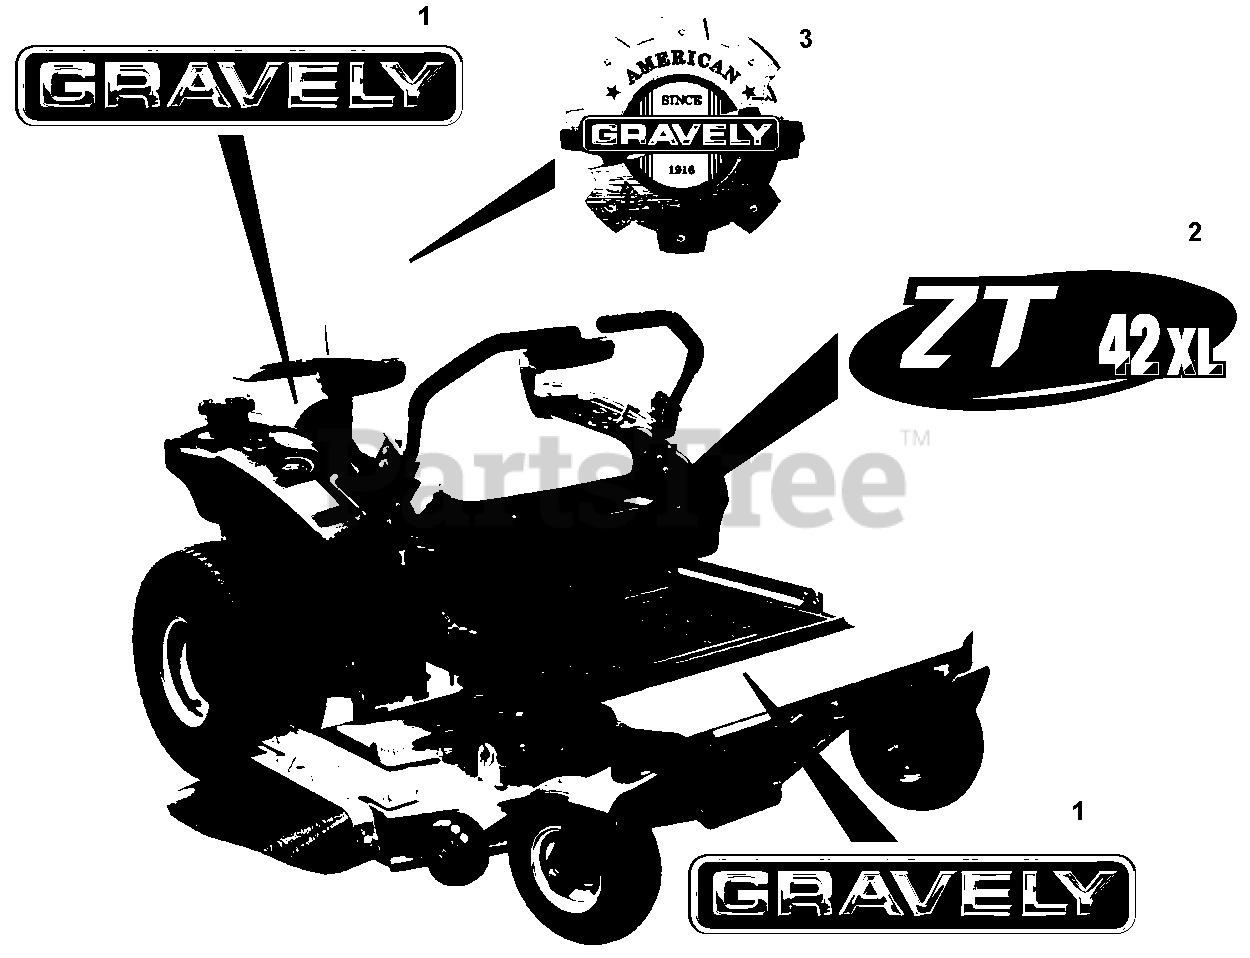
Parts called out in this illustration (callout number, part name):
1	Decal, Gravely Logo
2	Decal, 42 ZT XL
2	Decal, 48 ZT XL
2	Decal, 54 ZT XL
3	Decal, Gravely American Heritage
